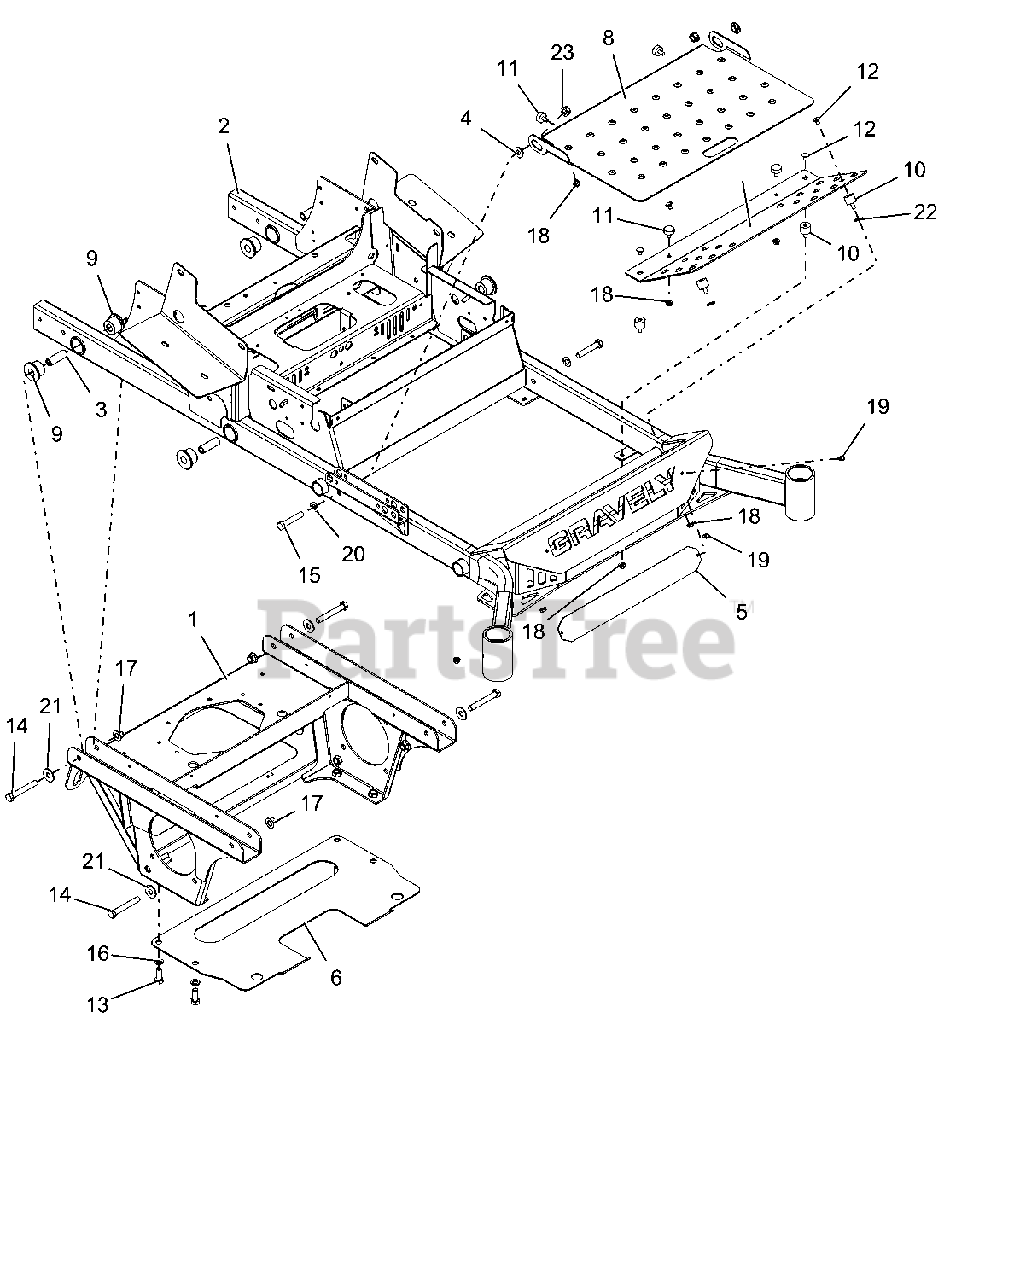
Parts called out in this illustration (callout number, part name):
1	WLDT, 200 PT AXLE/ENGINE FRAME
2	WLDMT, 52-66" PT400 MAIN FRAME-RED
3	SPCR, .50 X .75 X 2.23 YZ
4	BSHG, FLANGE .515X.750X.31X1.12
5	PLATE, BUMPER LOGO BACKING-BLACK
6	PLATE-TRANSMISSION SKID-RED
7	WLDMT, FOOTREST
8	WLDMT, FOOTREST
9	BSHG, FLANGE .750 X 1.510 X 1.130 X 2.000
10	BUMPER, STUD MOUNTED W/FEMALE INSERT
11	BUMPER, RUBBER
12	BLT-RDHDSQNK .31-18X.50 G5 YWZC
13	BLT-HEX .50-13X1.25 GR5 YWZC
14	BLT-HEX .50-13X3.50 GR5 YWZC
15	BLT-HEX .50-13X2.75 GR5 YWZC
16	WSHR-LK .50X.125 REG YWZC
17	NUT-LK-NYL-FLG .50-13 YWZC
18	@NUT-SPNLK-FLG .312-18 YWZC
19	SCR-TAP .25-20X.50 HWH TR YWZ
20	WSHR-FL-STL .531X1.000X.063 YWZC
21	WSHR-FL-STL.563X1.38X.109YWZC
22	WSHR-FL-STL.38X.875X.083 YWZC
23	NUT-LK-CTR-FLG .50-13 YWZC
